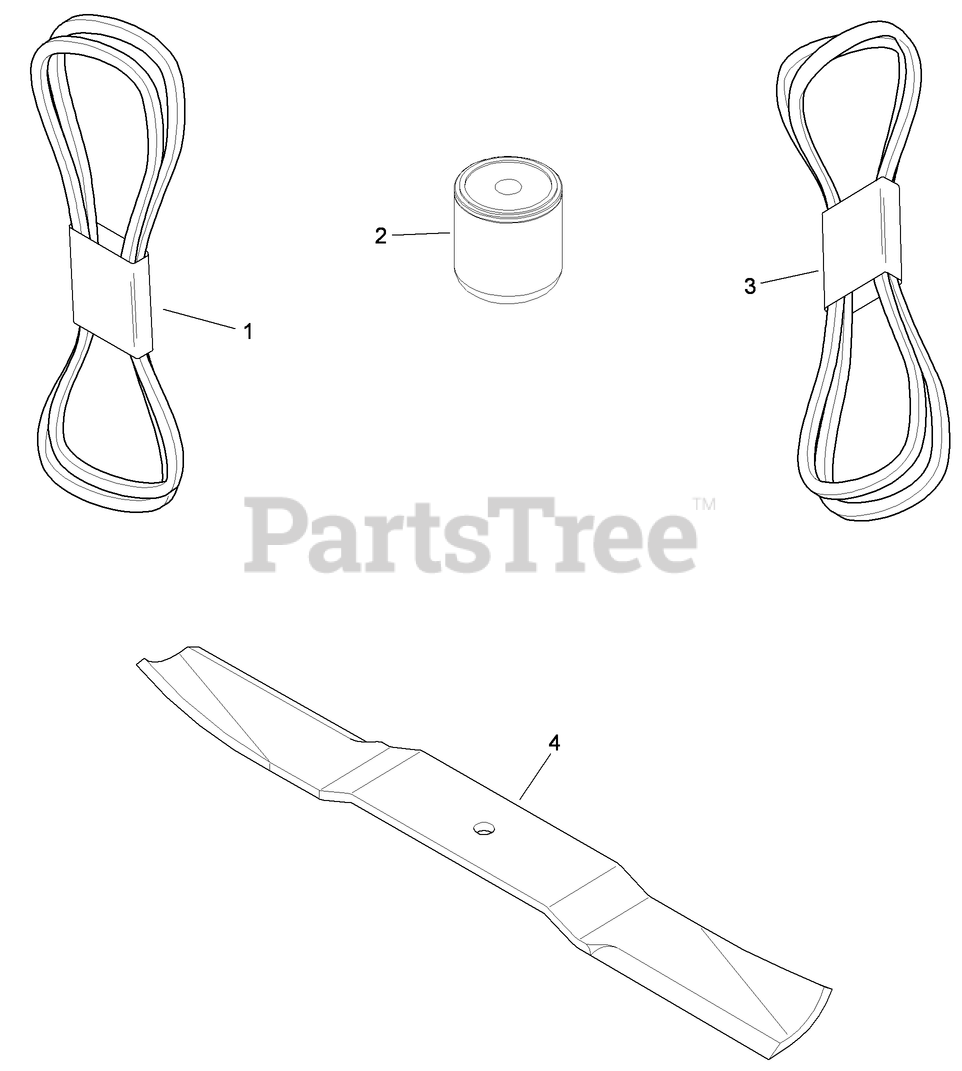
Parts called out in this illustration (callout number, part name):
1	BELT (52)
2	FILTER-OIL, HYD
3	V-BELT
4	BLADE-18 INCH
